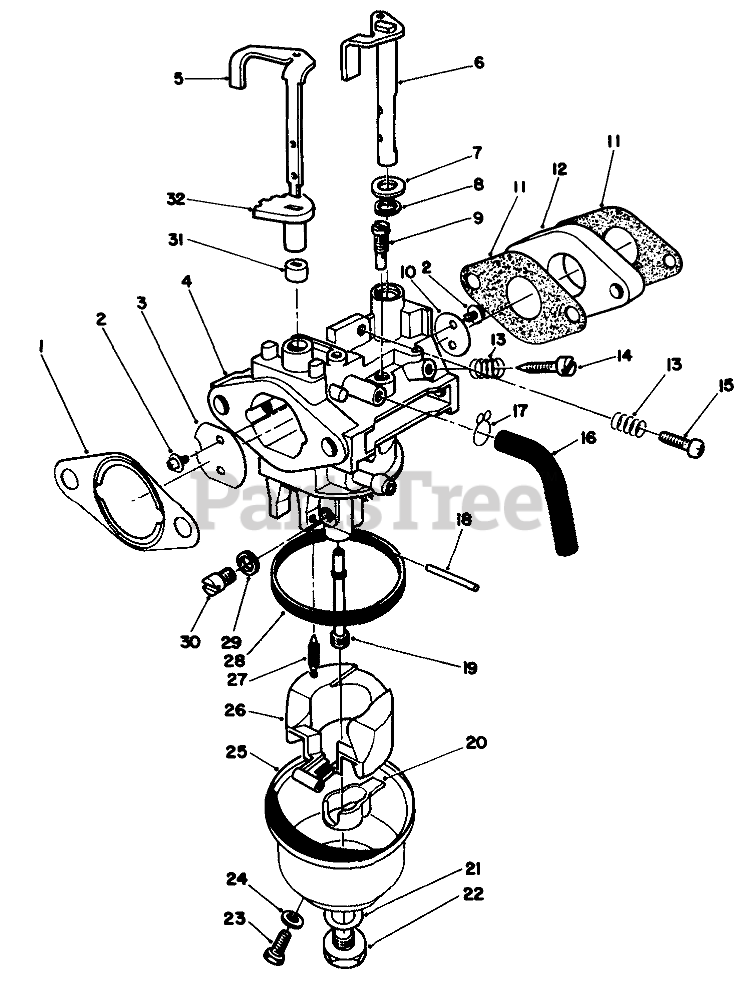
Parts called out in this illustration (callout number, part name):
1	GASKET F/W ENGINE
2	Screw
3	VALVE
4	Body-Carburetor
5	Shaft-Choke Valve
6	SHAFT
7	WASHER
8	Seal-Throttle Shaft
9	PILOT JET
10	VALVE
11	Gasket-Carburetor
12	CARB INSULATOR
13	SPRING-PILOT SCREW
14	ADJUSTER
15	SCREW
17	CLAMP
18	Pin
19	NOZZLE
20	SPACER
21	GASKET
22	SCREW
23	SCREW
24	GASKET
26	FLOAT
27	NEEDLE
28	FLOAT BOWL GASKET
29	SPACER
30	MAIN JET
31	LOWER CHOKE RING
32	UPPER CHOKE RING
